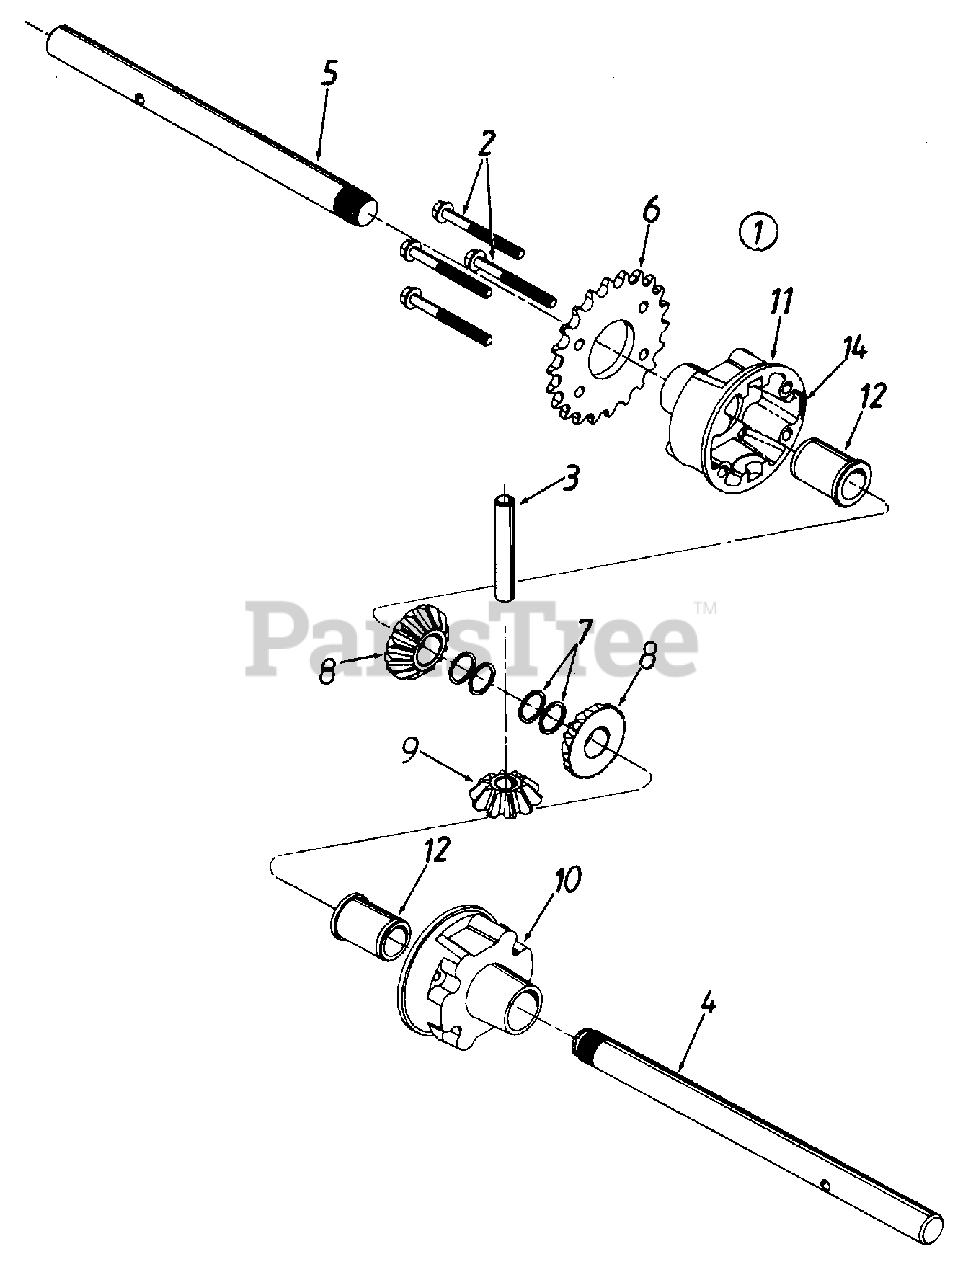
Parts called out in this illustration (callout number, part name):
1	DIFFERENTIAL ASSY COMPLETE
2	SCREW - HEX
3	SHAFT - CROSS
4	AXLE - SHAFT 10.95" LONG
5	AXLE - SHAFT 9.82" LONG
6	SPROCKET 22 T
7	RING - RETAINING 2 PER AXLE
8	GEAR - DIFFERENTIAL 14T
9	GEAR - DIFFERENTIAL 10T
10	HOUSING - DIFFERENTIAL RH
11	HOUSING - DIFFERENTIAL LH
12	BEARING - FLANGE
